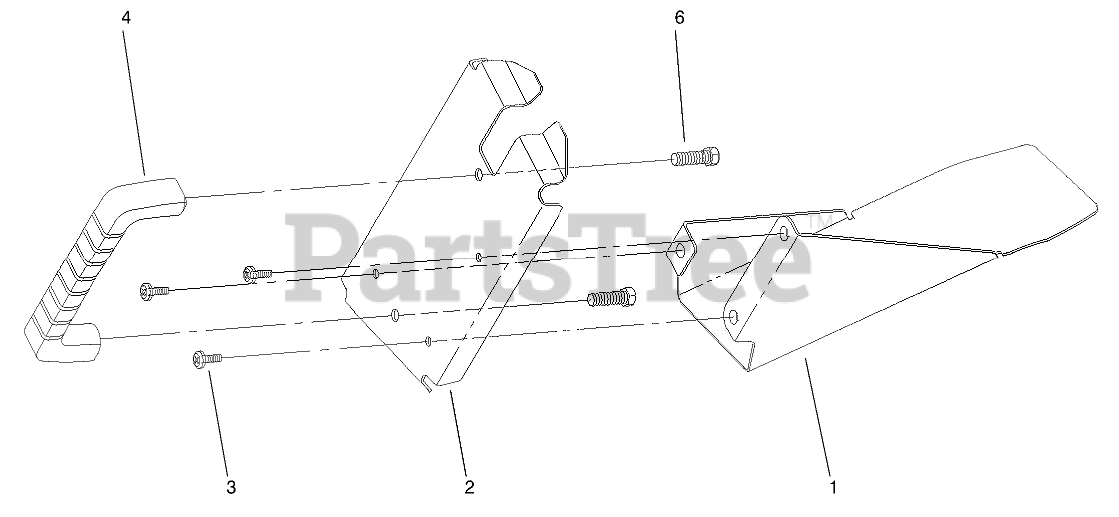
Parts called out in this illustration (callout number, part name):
1	SHIELD - DISCHARGE PLUG
2	COVER - DISCHARGE PLUG
4	HANDLE-DOOR
6	SCREW-HWH
